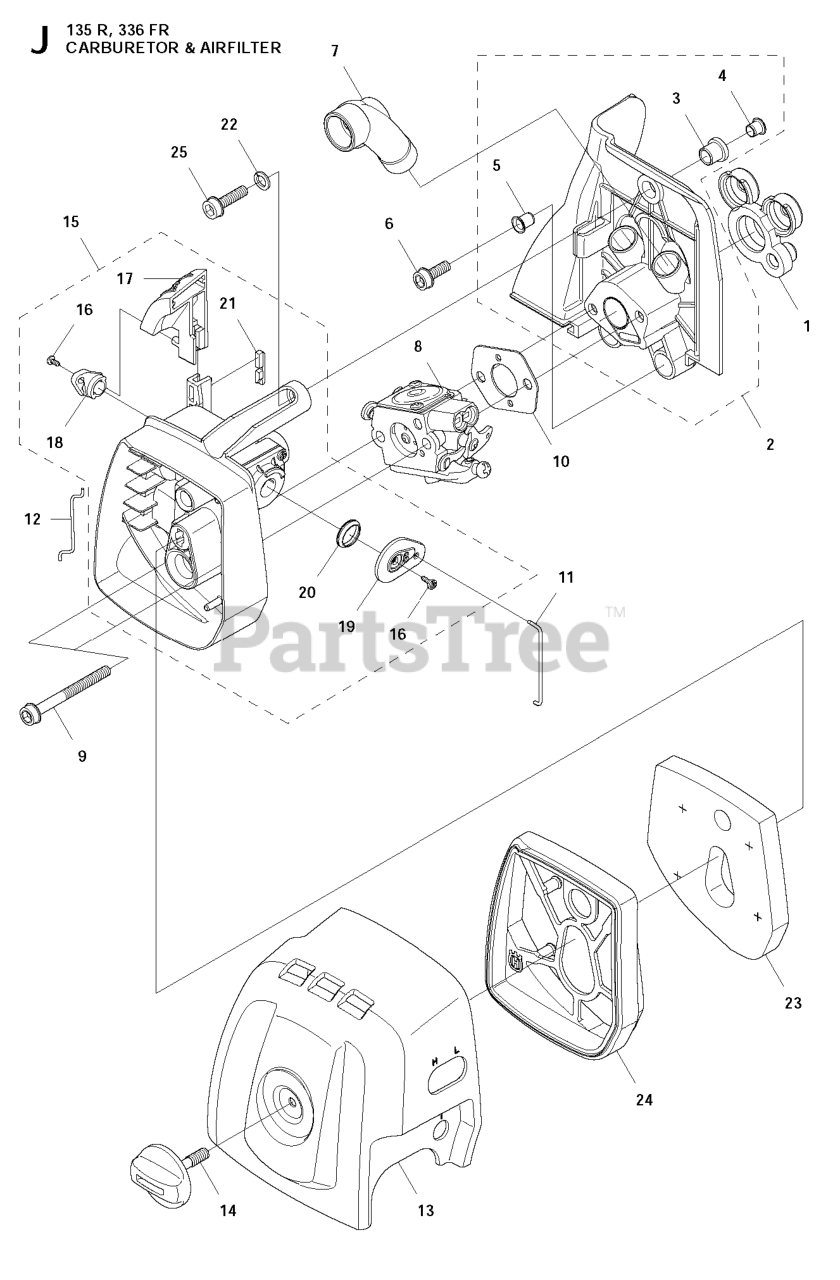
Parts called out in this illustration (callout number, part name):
8	CARBURETOR
11	THROTTLE ROD
12	THROTTLE ROD
13	FILTER COVER
15	FILTER HOLDER ASSY
17	CHOKE CONTROL
18	CHOKE LEVER
